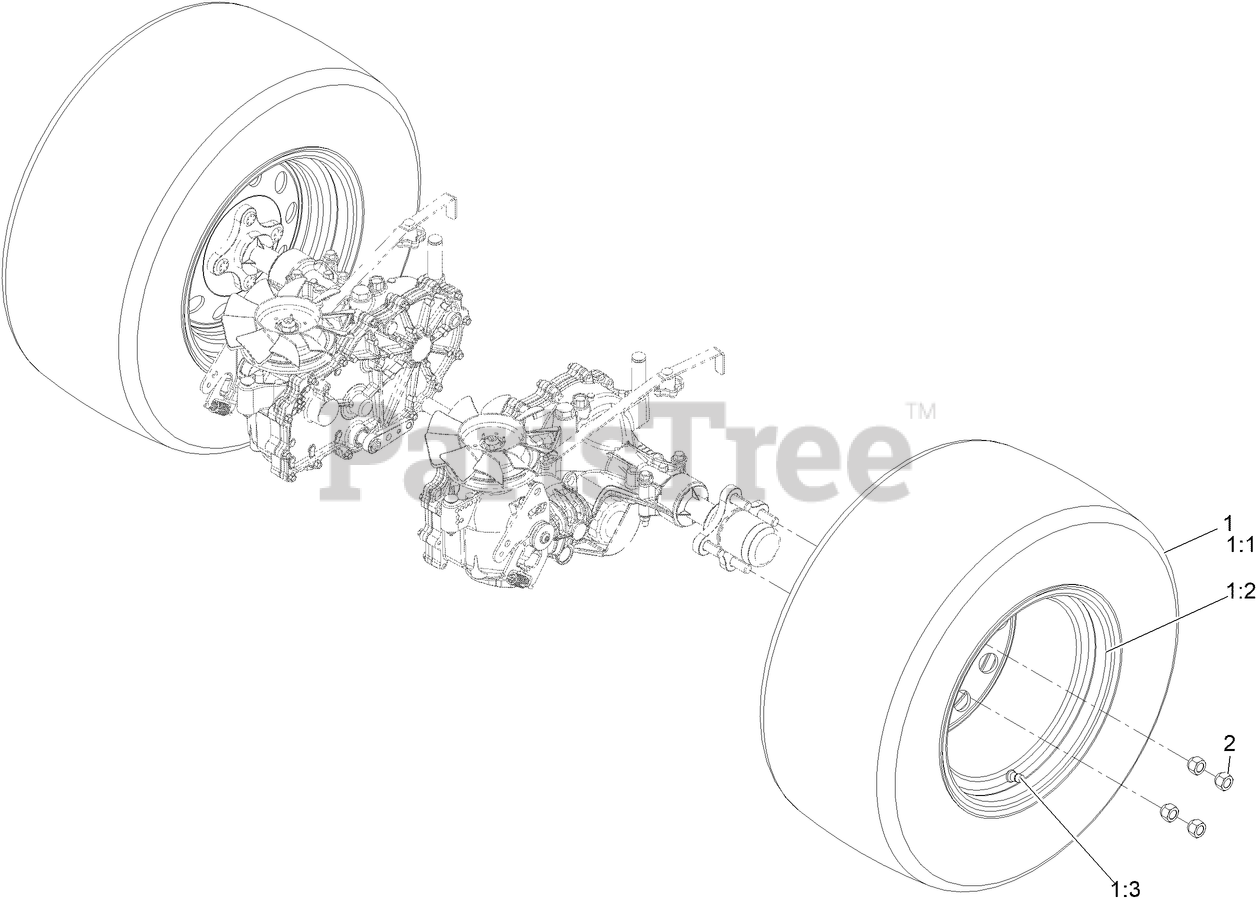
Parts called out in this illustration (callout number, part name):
1	WHEEL AND TIRE ASM
1:1	TIRE 23 X 10.50-12
1:3	VALVE
2	NUT-LUG
